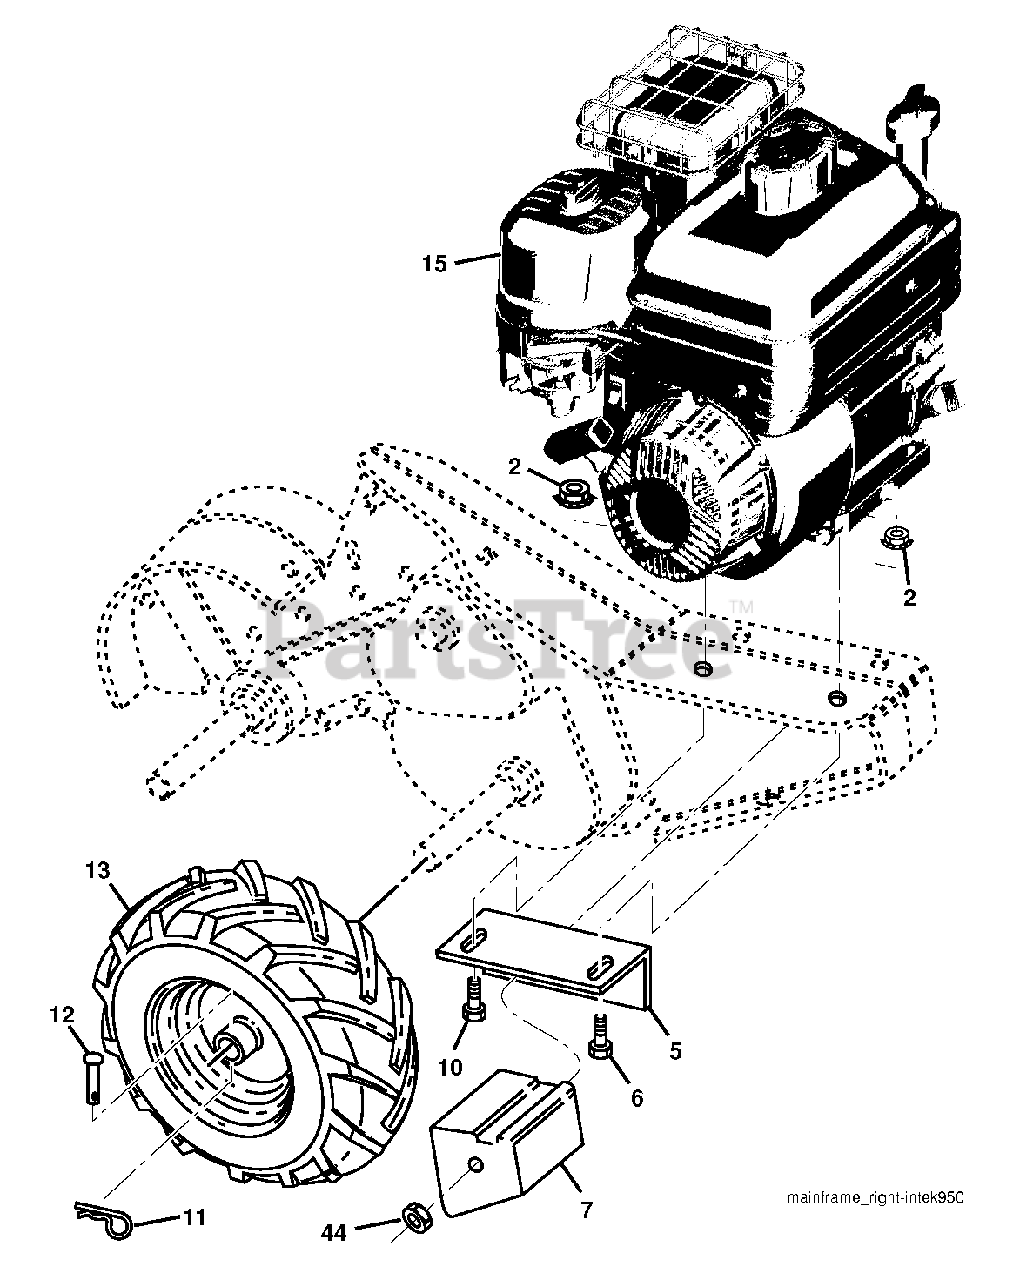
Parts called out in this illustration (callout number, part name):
2	LOCKNUT-FLANGE 5/16-18
5	BRACKET.REINFORCEMENT.RH.BLACK
6	BOLT, HEX 5/16-18X1-3/4
7	COUNTERWEIGHT.RH
10	BOLT
11	RETAINER M
12	RIVET
13	Wheel Assembly, CRT RH 13 X 5 X 6 Silver
